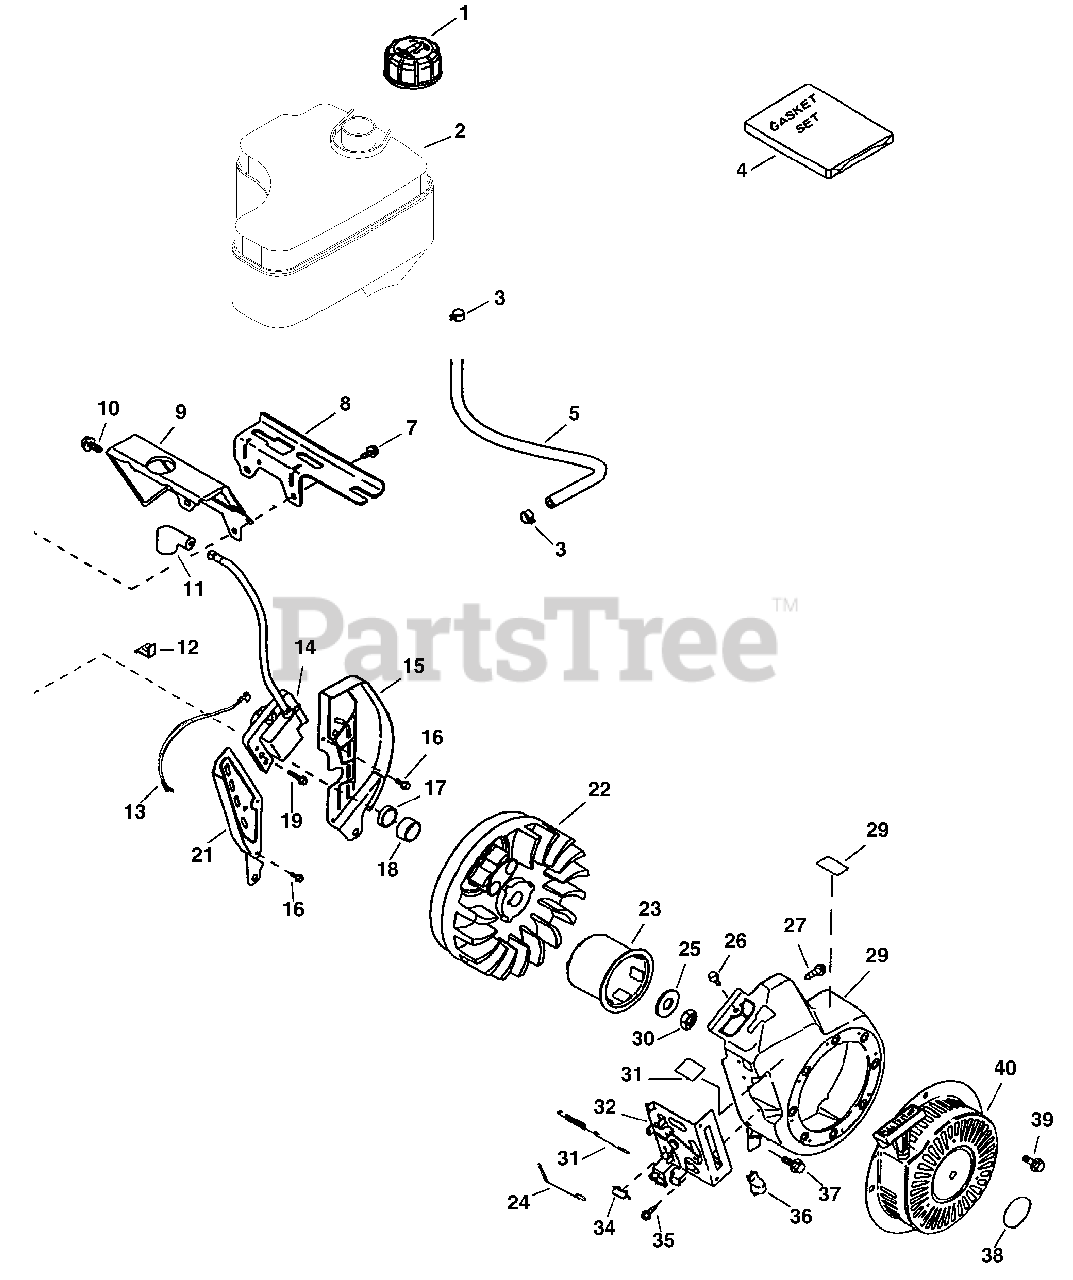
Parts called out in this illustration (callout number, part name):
1	Fuel Cap
2	Fuel Tank
3	Fuel Line Clamp
4	Gasket Set
5	Fuel Line
7	Screw, 1/4-20 x 7/8"
8	Fuel Tank Bracket
9	Blower Housing Extension
10	Screw, 10-24 x 9/16"
11	Spark Plug Cover
12	Wire Clip
13	Ground Wire
14	Solid State Ignition
15	Air Baffle (Right)
16	Screw, 10-24 x 9/16"
19	Screw, Torx T-15, 15/16"
21	Air Baffle (Left)
23	Starter Cup
24	Governor Link
25	Bell Washer
26	Screw, 1/4-20 x 31/64"
27	Screw, 10-32 x 1/2"
29	Blower Housing
30	Flywheel Nut
31	Speed Control Decal
32	Control Bracket
35	Screw, 10-32 x 1/2"
36	Control Knob
37	Screw, 1/4-20 x 31/64"
38	Starter Decal
39	Screw, 1/4-20 x 31/64"
40	Rewind Starter
